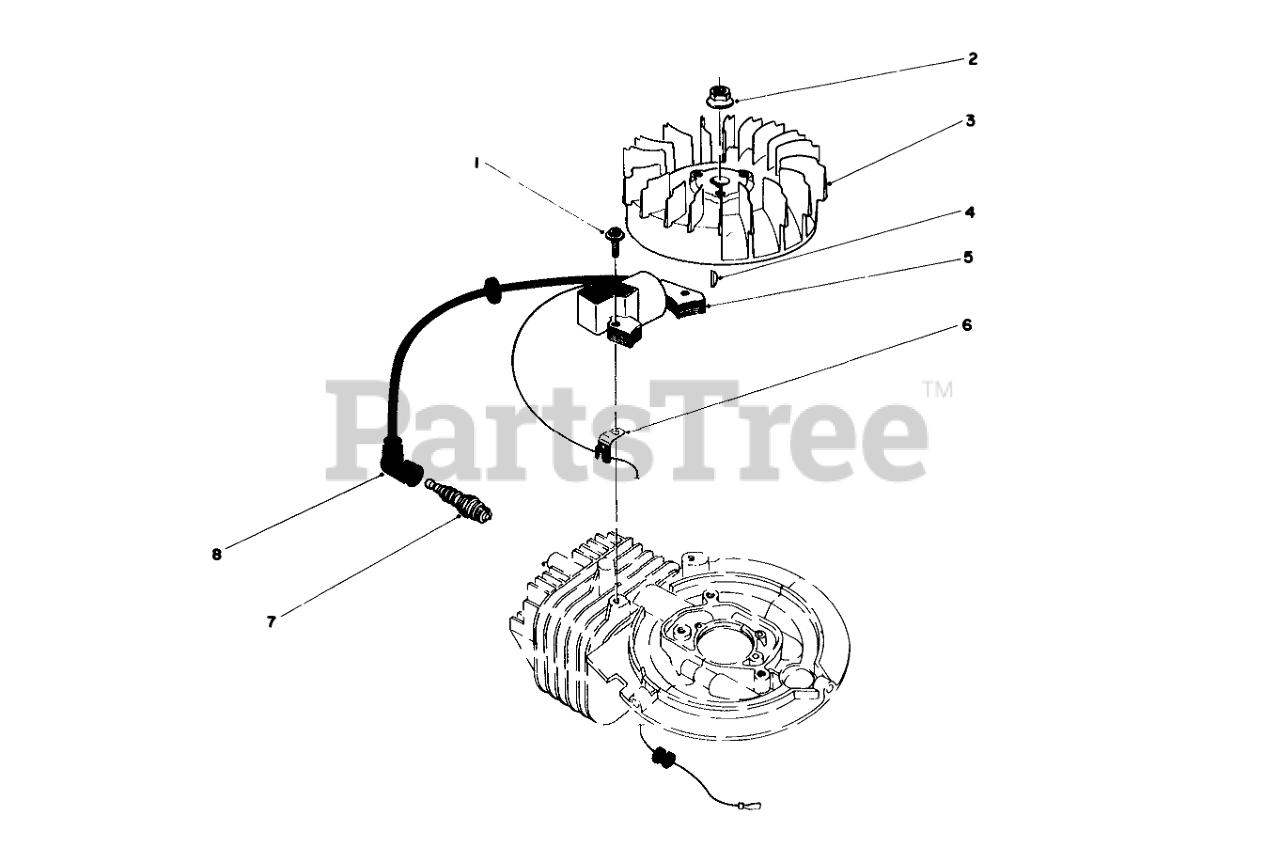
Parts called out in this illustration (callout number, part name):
1	Allenhead
3	FLYWHEEL
5	COIL-MAGNETO
6	CLAMP
7	Sparkplug
8	CAP-SPARKPLUG
